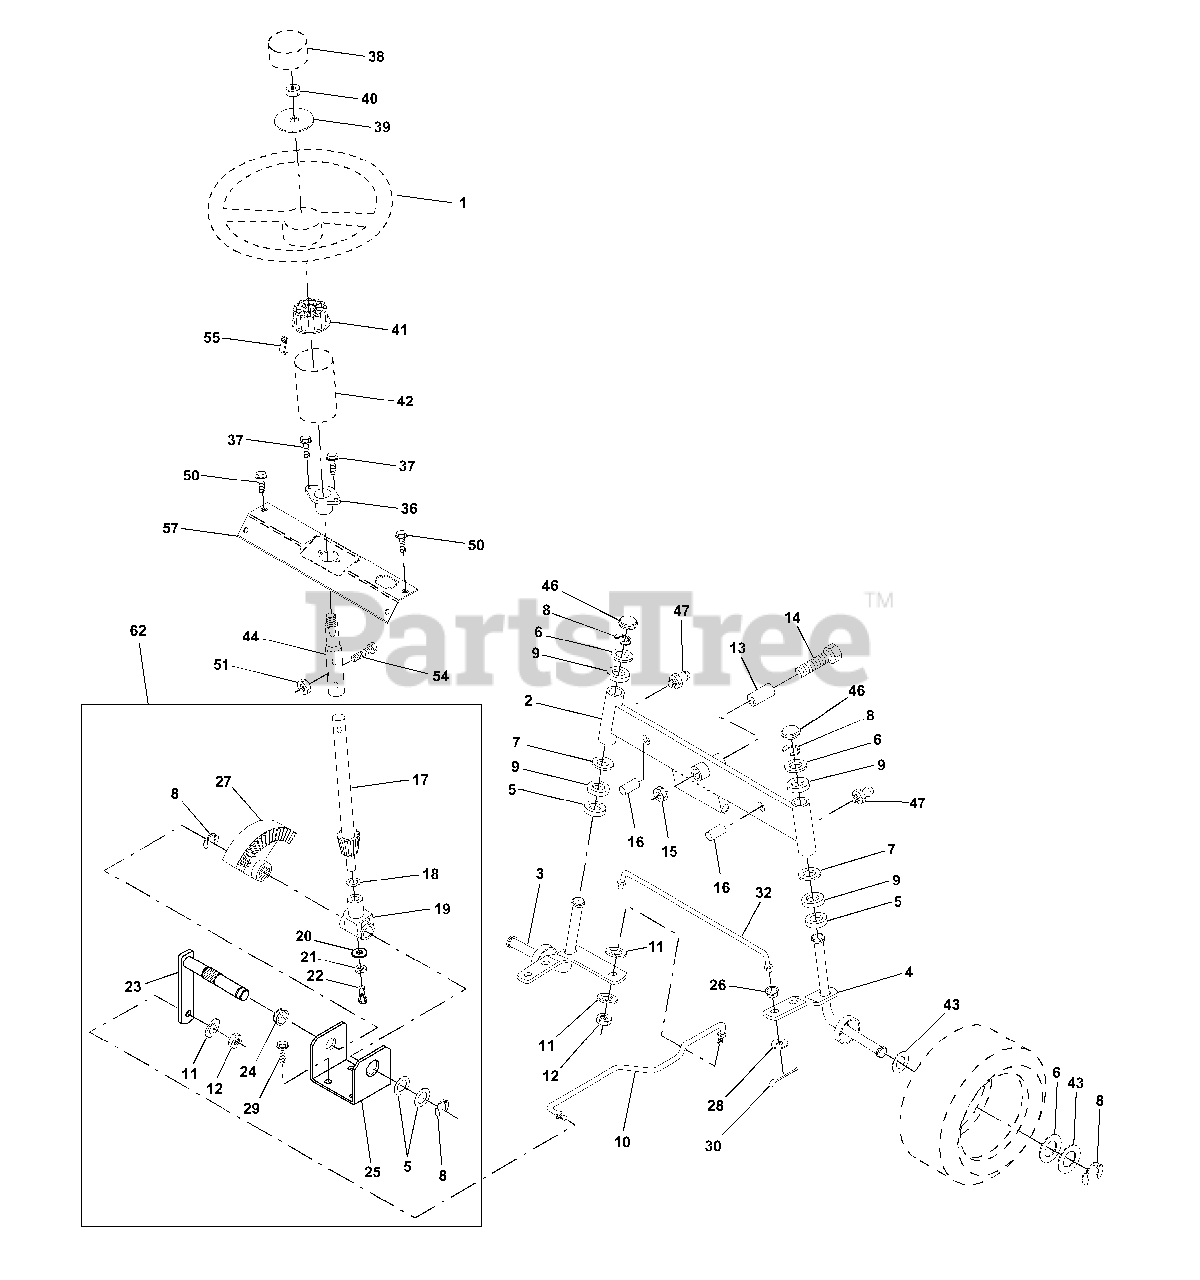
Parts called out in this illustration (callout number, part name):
1	Wheel Steering Auto Grey
2	Axle Asm Fr LT W/gzks 38/42
3	Spindle Asm LH
4	Spindle Asm RH
5	Bearing Race Thrust Harden
6	Washer 25/32 X 1-5/8 X 16 Ga
7	Washer 27/32 X 1-1/4 X 16 Ga
8	Ring Klip #t5304-75
9	Bearing Col Strg Blk
10	Link Drag Sol Ball Jt 20 064
11	Washer Lock Hvy Hlcl Spr 3/8
12	Nut Fin Hex 3/8-24 Unf
13	Spacer Bearing Axle Front
14	Bolt Hex 5/8-11 Unc X 3-1/2
15	Nut Lock Flange 5/8-11 Unc
16	Pin Axle 5/8 X 1 55/1 54 Lg
17	Shaft Asm Strg Private Label
18	Washer Thrust 515x 750x 033
19	Support Shaft
20	Washer Shim 1/4 X 5/8 X 062
21	Washer Lock Hvy Helical 1/4
22	Screw Hex Socket 1/4-20 X 5/8
23	Shaft Asm Pittman
24	Nyliner Snap In
25	Bracket Steering
26	Bushing Link Drag Blk LR
27	Gear Sector
28	Washer 13/32 X 7/8 X 16 Ga
29	Screw Thdrol 3/8-16x3/4 Ty-tt
30	Pin Cotter 1/8 X 3/4 Cad
32	Rod Tie Wire Form 19 75 Mech
36	Bushing Strg
37	Screw Slftp #10-16 X 1/2 Ty-b
38	Insert Cap Strg Wh Au
39	Washer 13/32 X 2-3/8 X 8 Ga
40	Nut Lock Center 3/8-24unf
41	Adaptor Wheel Strg 640/ 635id
42	Boot Steering Shaft
43	Washer 25/32 X 1 1/4 X 16 Ga
44	Shaft Extension Steering
46	Cap Spindle Fr Top Blk
47	Fitting Grease
50	Screw Hex Wsh Thdrol 1/4-20 x 3/4
51	Nut Lock Hex w/Ins 5/16-18
54	Bolt Fin Hex 5/16-18 Unc x 1-1/4
55	Clip Tinnerman
57	Support Shaft Steering
62	Kit, Steering Assembly
